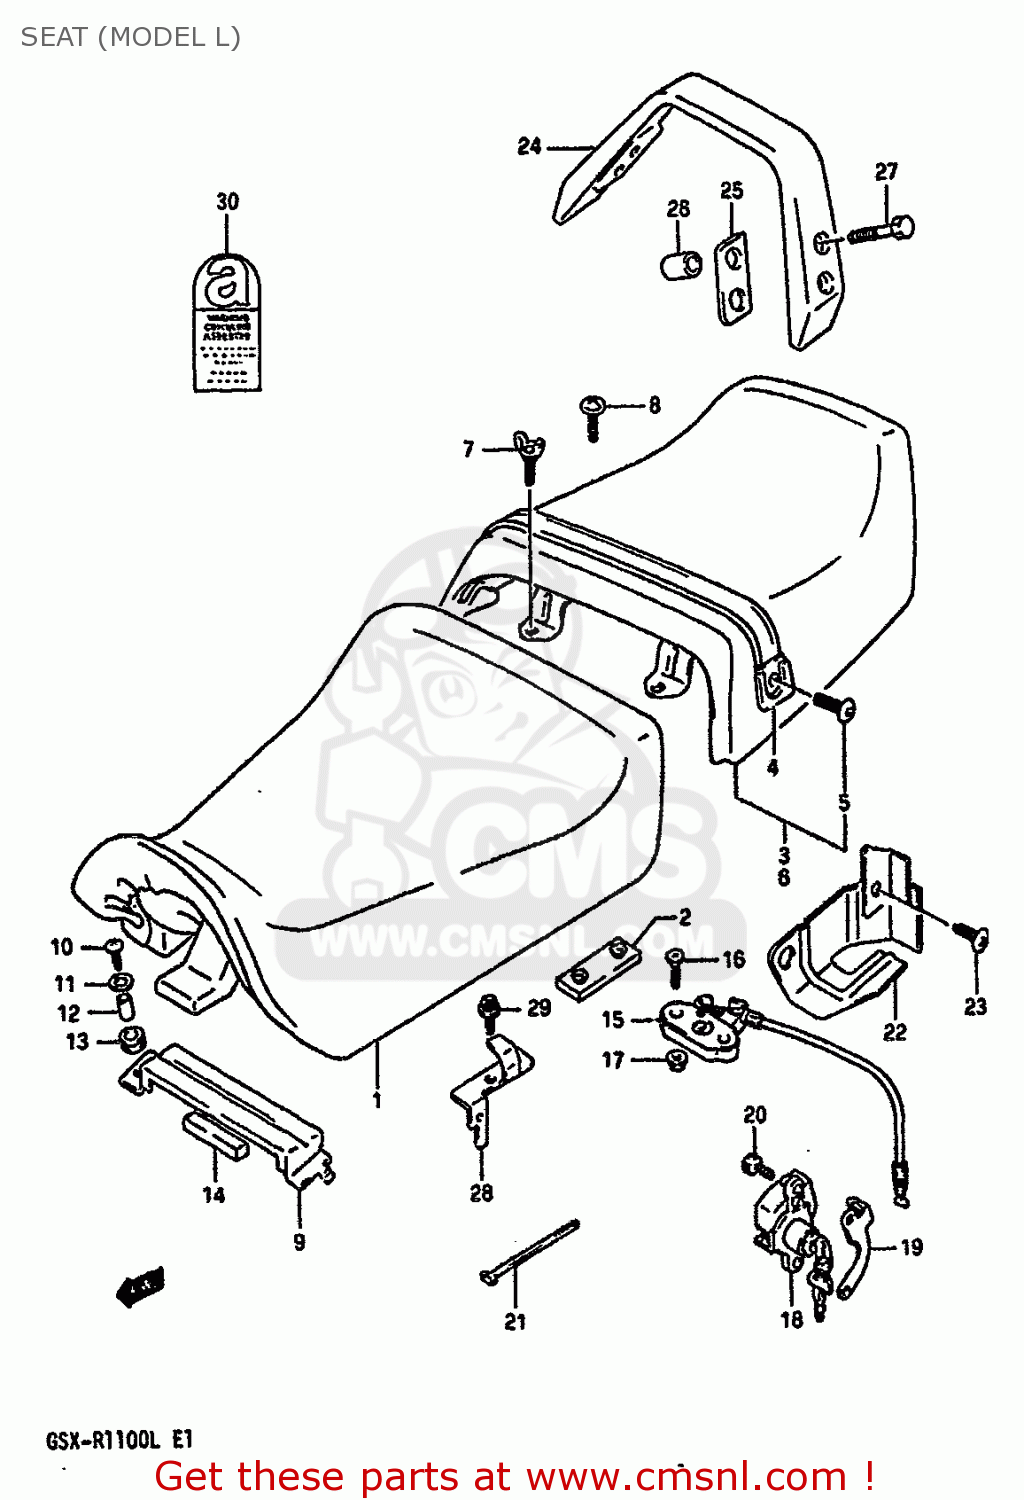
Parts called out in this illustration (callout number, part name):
1	SEAT ASSEMBLY
2	CUSHION
3	SEAT ASSEMBLY,PILLION (BLUE)
4	BAND,SEAT
5	BOLT
6	SEAT ASSEMBLY,PILLION
7	BOLT
8	SCREW(6X20)
9	PLATE,SEAT SUPPORT,REAR
10	SCREW, CENTER
11	WASHER
12	SPACER (6.1X8X9.5)
13	CUSHION
14	CUSHION,PLATE SEAT SPRING
15	BRACKET,SEAT SUPPORT RR
16	SCREW
17	NUT
18	LOCK SET,SEAT
19	PLATE,SEAT LOCK
20	BOLT
21	CLAMP
22	PLATE,SEAT LOCK CABLE
23	BOLT 6X16
24	HANDLE,PILLION RIDER
25	CUSHION,PILLION RIDER HANDLE
26	BOLT
27	BOLT
28	BOLT
29	BOLT
30	LABEL,ASBESTOS WARNING
